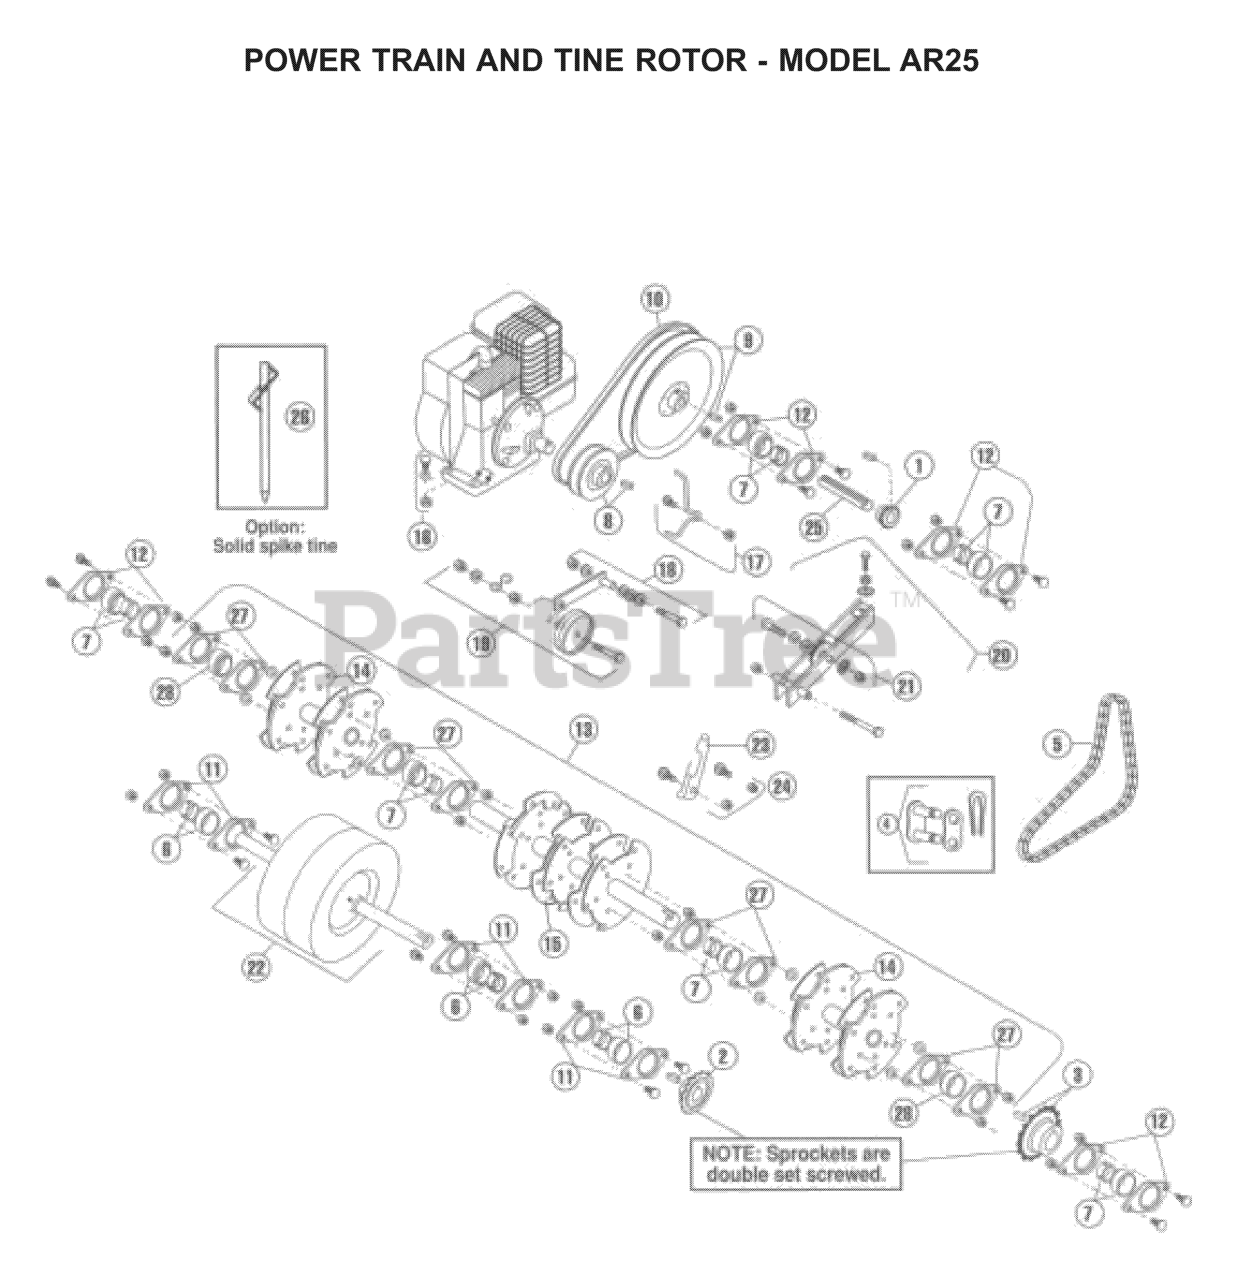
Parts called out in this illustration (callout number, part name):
1	SPROCKET
2	SPROCKET
3	SPROCKET
4	CHAIN LINK #50
5	CHAIN, #50 PERMA LUBE ROLLER
6	BEARING
7	BEARING 1"
8	V-PULLEY, A-4"X3/4" BORE W/KEY
9	V-PULLEY
10	ENGINE BELT - V
11	STAMPING KIT
12	STAMPING KIT
13	TINE ROTOR
14	OUTER ROTOR
15	CENTER TINE
16	FASTENER KIT
17	BELT KEEPER KIT
18	IDLER ARM KIT
19	IDLER PULLEY KIT
20	IDLER ARM KIT
21	IDLER SPROCKET KIT
22	FRONT WHEEL & SHAFT KIT
23	TINE SET
24	BOLT KIT
25	JACK SHAFT, W/ KEY
26	SPIKE SET NLA
27	STAMPING KIT
28	BEARING
540007103	BOLT KIT
540007112	TINE SET
